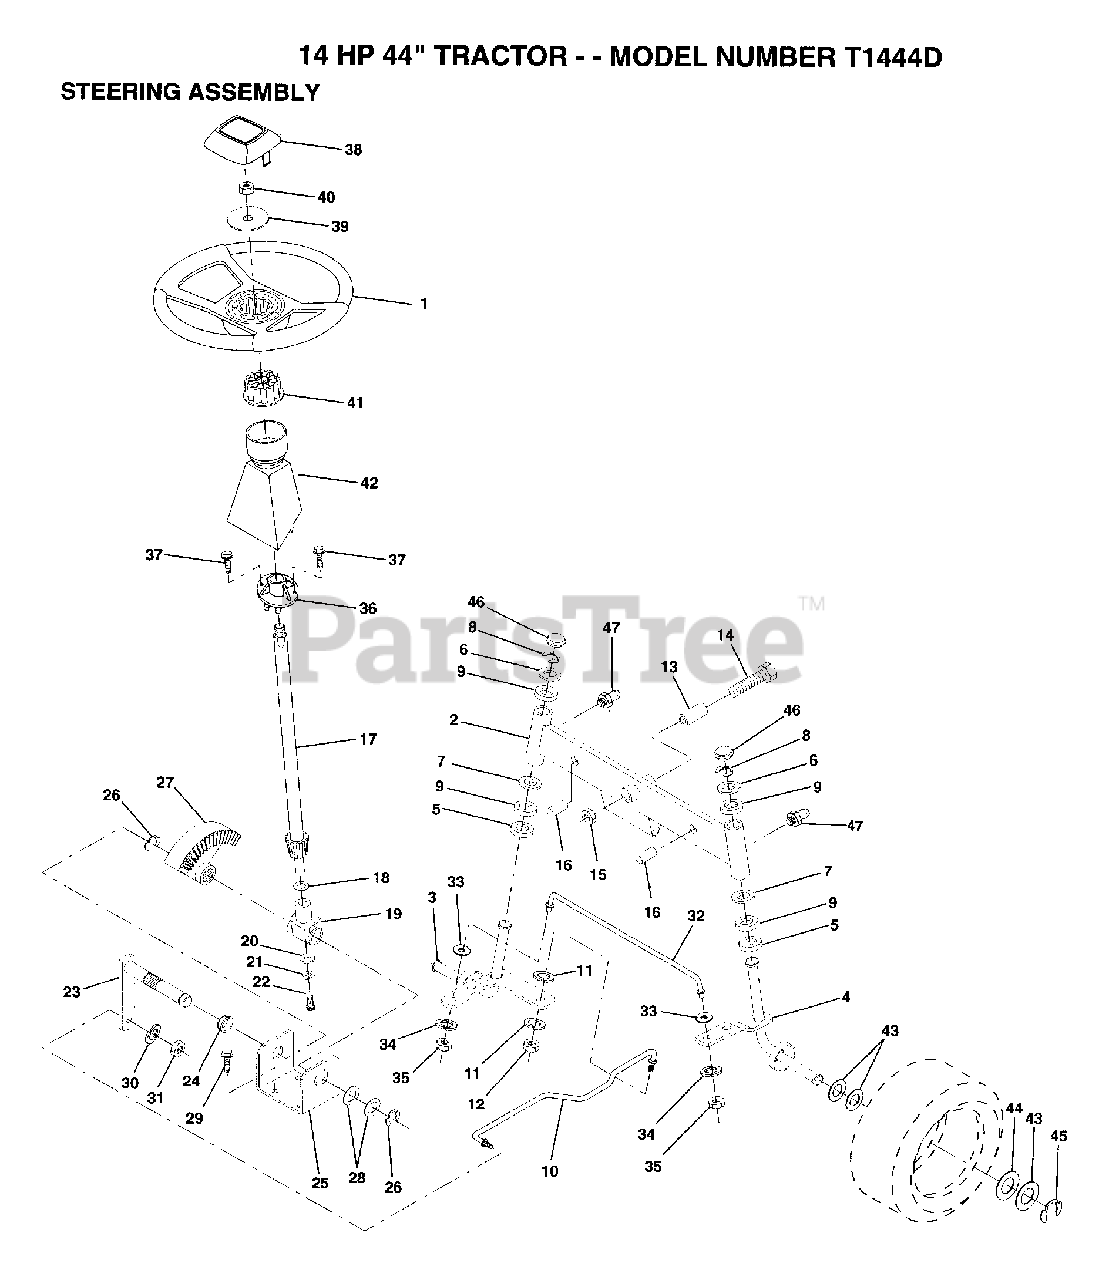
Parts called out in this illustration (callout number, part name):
2	FRONT AXLE
3	SPINDLE LH
4	SPINDLE RH
5	WASHER .T
6	WASHER
7	WASHER
8	RING
9	COL. SRTG. BEAR.
11	LOCKWASHER
13	BEARING
14	BOLT LT
15	"NUT-LOC,FLANGE LT"
16	AXLE PIN
17	SHAFT ASM
18	THRUST WASHER
19	SUPPORT.SHAFT
21	LOCKWASHER
22	"SCREW,SPECIAL"
24	NYLINER T
25	"BRKT,STEERING"
26	RING
27	GEAR SECTOR
28	WASHER .T
29	SCREW
30	LOCKWASHER
32	TIE ROD
33	WASHER M
34	LOCKWASHER
35	NUT.LOCK.5/16-24
38	ST WHL INSERT CAP
39	WASHER T
40	GRIPCO NUT
41	ADAPTER-WHEEL LT
42	"TUBE, STR SHAFT"
43	WASHER
44	WASHER
45	RING
46	CAP
47	ZERK M
